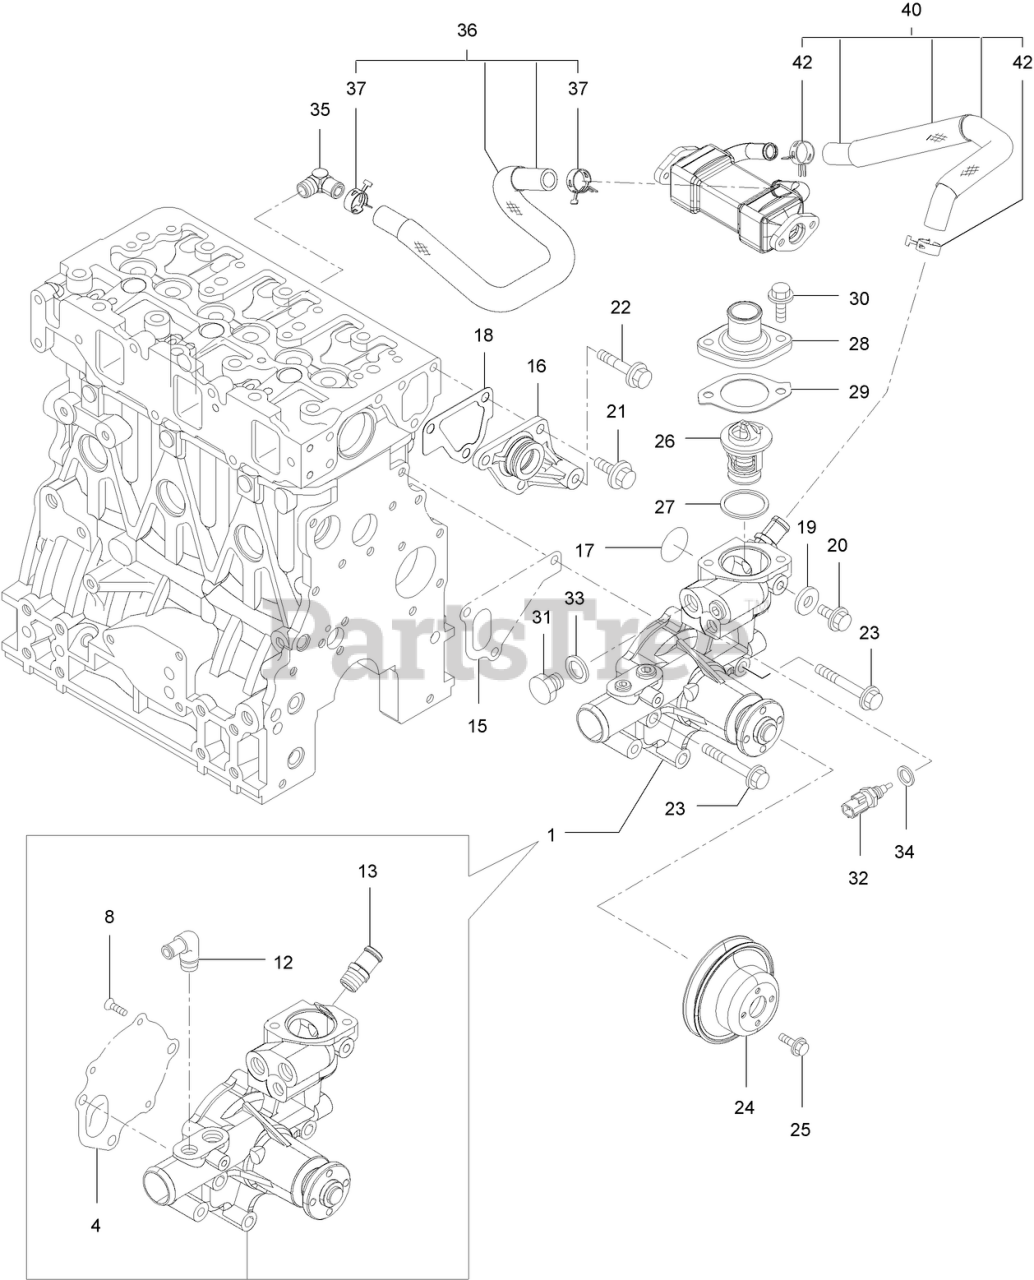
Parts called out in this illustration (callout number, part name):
1	WATER PUMP ASM
4	GASKET
8	SCREW-FLAT
15	GASKET
17	O-RING
18	GASKET
19	GASKET
24	PULLEY-V, PUMP
26	THERMOSTAT
27	GASKET
28	COVER-THERMOSTAT
29	GASKET
32	SENSOR-THERMOSTAT, CW
33	GASKET
34	WASHER-SEAL
36	E G R-C PIPE ASM
37	CLIP-HOSE
40	PIPE ASM, CW
42	CLIP-HOSE
